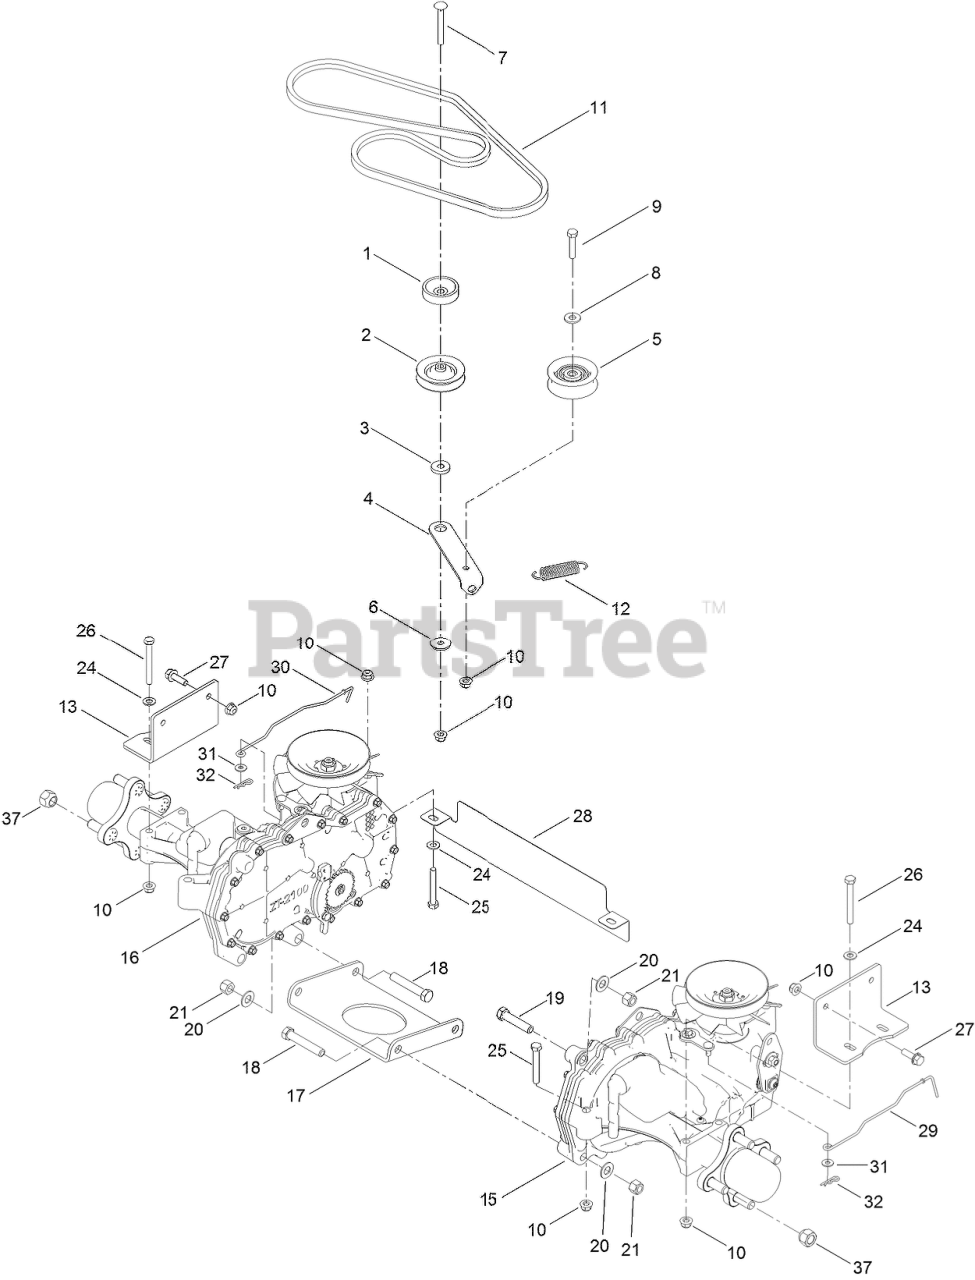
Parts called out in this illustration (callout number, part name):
1	SPACER
2	PULLEY-IDLER
3	SPACER-IDLER ARM
4	ARM-IDLER
5	PULLEY-IDLER, FLAT
6	WASHER-PIVOT
7	SCREW-CARR
8	WASHER-FLAT
9	SCREW-HH
10	NUT-HF
11	V-BELT
12	SPRING-PEDAL, RETURN
13	MOUNT-HYDRO
15	LH HYDRO TRANSAXLE ASM
16	RH HYDRO TRANSAXLE ASM
17	PLATE-CROSS, HYDRO
18	SCREW-HH
19	SCREW-HH
20	WASHER-FLAT
21	NUT-HEX, NI
24	WASHER-PLAIN
25	SCREW-HH
26	SCREW-HH
27	SCREW-HHF
28	GUARD REAR, NARROW
29	ROD-BYPASS, LH
30	ROD-BYPASS, RH
31	WASHER
32	PIN-HAIR
37	NUT-LUG
